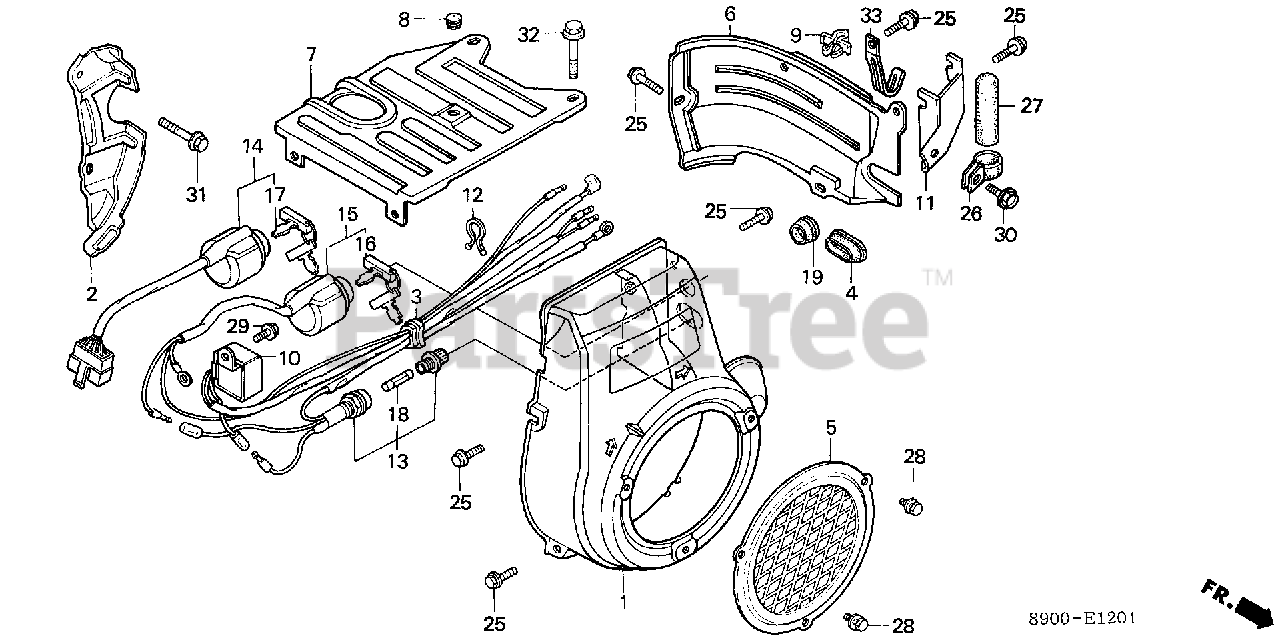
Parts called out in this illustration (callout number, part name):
1	COVER, FAN *R8* (BRIGHT RED)
2	PLATE, SIDE
3	GROMMET, SWITCH CORD
5	PROTECTOR, FAN COVER *R8* (BRIGHT RED)
6	SHROUD *R8* (BRIGHT RED)
7	COVER, TOP *R8* (BRIGHT RED)
8	GROMMET, TOP COVER
9	CLIP, IGNITION WIRE (8MM)
10	RECTIFIER, SILICON (NOT AVAILABLE)
11	STAY, CLAMP
12	CLIP, PURSE LOCK
13	HOLDER, FUSE (1.5A) (NOT AVAILABLE)
14	SWITCH ASSY., COMBINATION
15	SWITCH ASSY., COMBINATION
16	KEY
17	KEY
18	FUSE (1.5A) (NOT AVAILABLE)
25	BOLT, FLANGE (6X12) (CT200)
26	CLIP, CORD
27	TUBE, CORD (25MM)
28	BOLT-WASHER (6X10)
29	BOLT, FLANGE (6X10)
30	BOLT, FLANGE (6X12)
31	BOLT, FLANGE (8X20)
